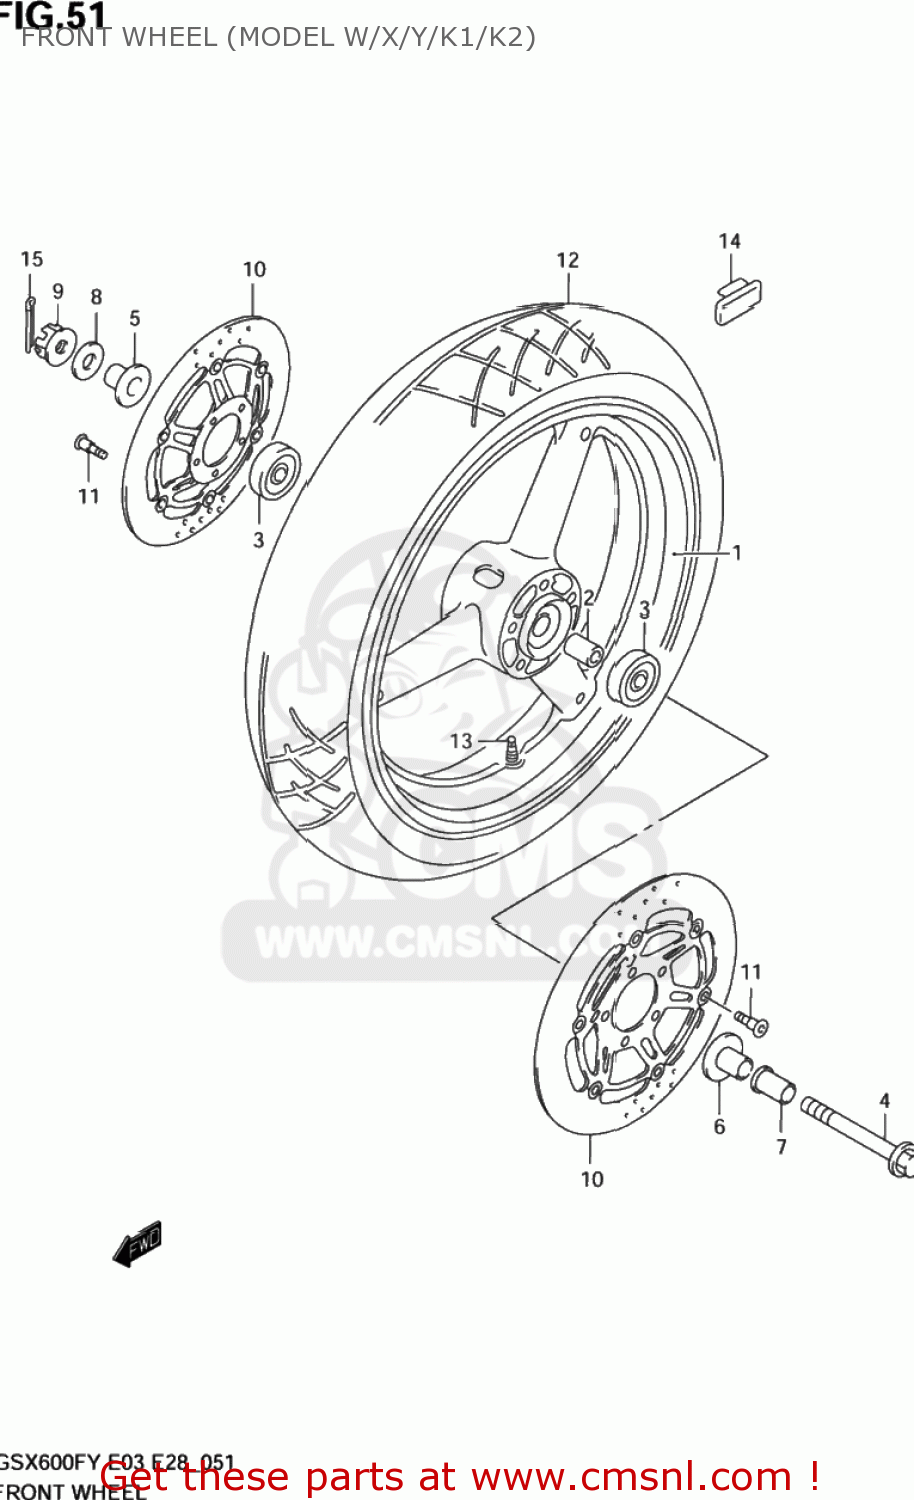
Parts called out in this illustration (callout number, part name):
1	WHEEL,FR(17XMT3.50)
2	SPACER(15.3X21.7X63)
3	BEARING
4	AXLE,FR
5	SPACER,FR AXLE
6	SPACER,FR AXLE,L
7	SPACER,FR AXLE,L
8	WASHER
9	NUT
10	DISC,FR BRAKE
11	BOLT 8X33
12	TIRE 120/70 ZR17 (58W),M
13	VALVE ASSEMBLY,WHEEL,TR412
14	BALANCER,WHEEL (10G)
15	COTTER PIN
